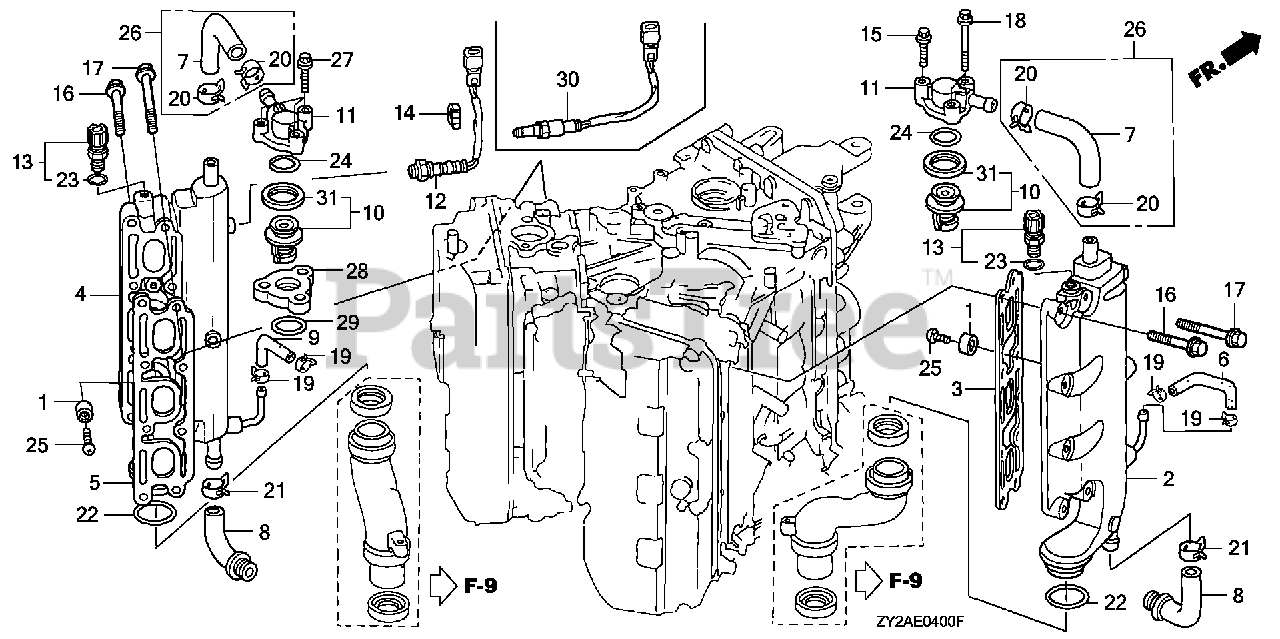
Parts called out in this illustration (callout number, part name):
1	METAL, ANODE
2	MANIFOLD, R. EX. *NH8* (DARK GRAY)
3	GASKET, R. EX. MANIFOLD
4	MANIFOLD, L. EX. *NH8* (DARK GRAY)
5	GASKET, L. EX. MANIFOLD
6	TUBE, R. WATER RETURN
7	TUBE, WATER RELIEF
8	TUBE, WATER
9	TUBE, L. WATER RETURN
10	THERMOSTAT ASSY.
11	COVER, THERMOSTAT *NH8* (DARK GRAY)
12	SENSOR, OXYGEN
13	SENSOR ASSY., WATER TEMPERATURE
14	CLIP, BRAKE PIPE (A) (FOR OXYGEN SENSOR)
15	BOLT, FLANGE (6X35)
16	BOLT, FLANGE (8X40)
17	BOLT, FLANGE (8X60)
18	BOLT, FLANGE (6X60)
19	CLAMP, TUBE (D10.5)
20	CLAMP, TUBE (D29)
21	CLAMP, TUBE (D21)
22	O-RING (66.4X3.1)
23	O-RING (9.5X1.9)
24	O-RING (31.5X2.4) (ARAI)
25	SCREW, PAN (6X18)
26	TUBE SET, WATER
27	BOLT, FLANGE (6X35)
27	BOLT, FLANGE (6X50)
28	SPACER, THERMOSTAT *NH8* (DARK GRAY)
29	O-RING (31.5X2.4) (ARAI)
30	SENSOR, OXYGEN
31	RUBBER, RING
